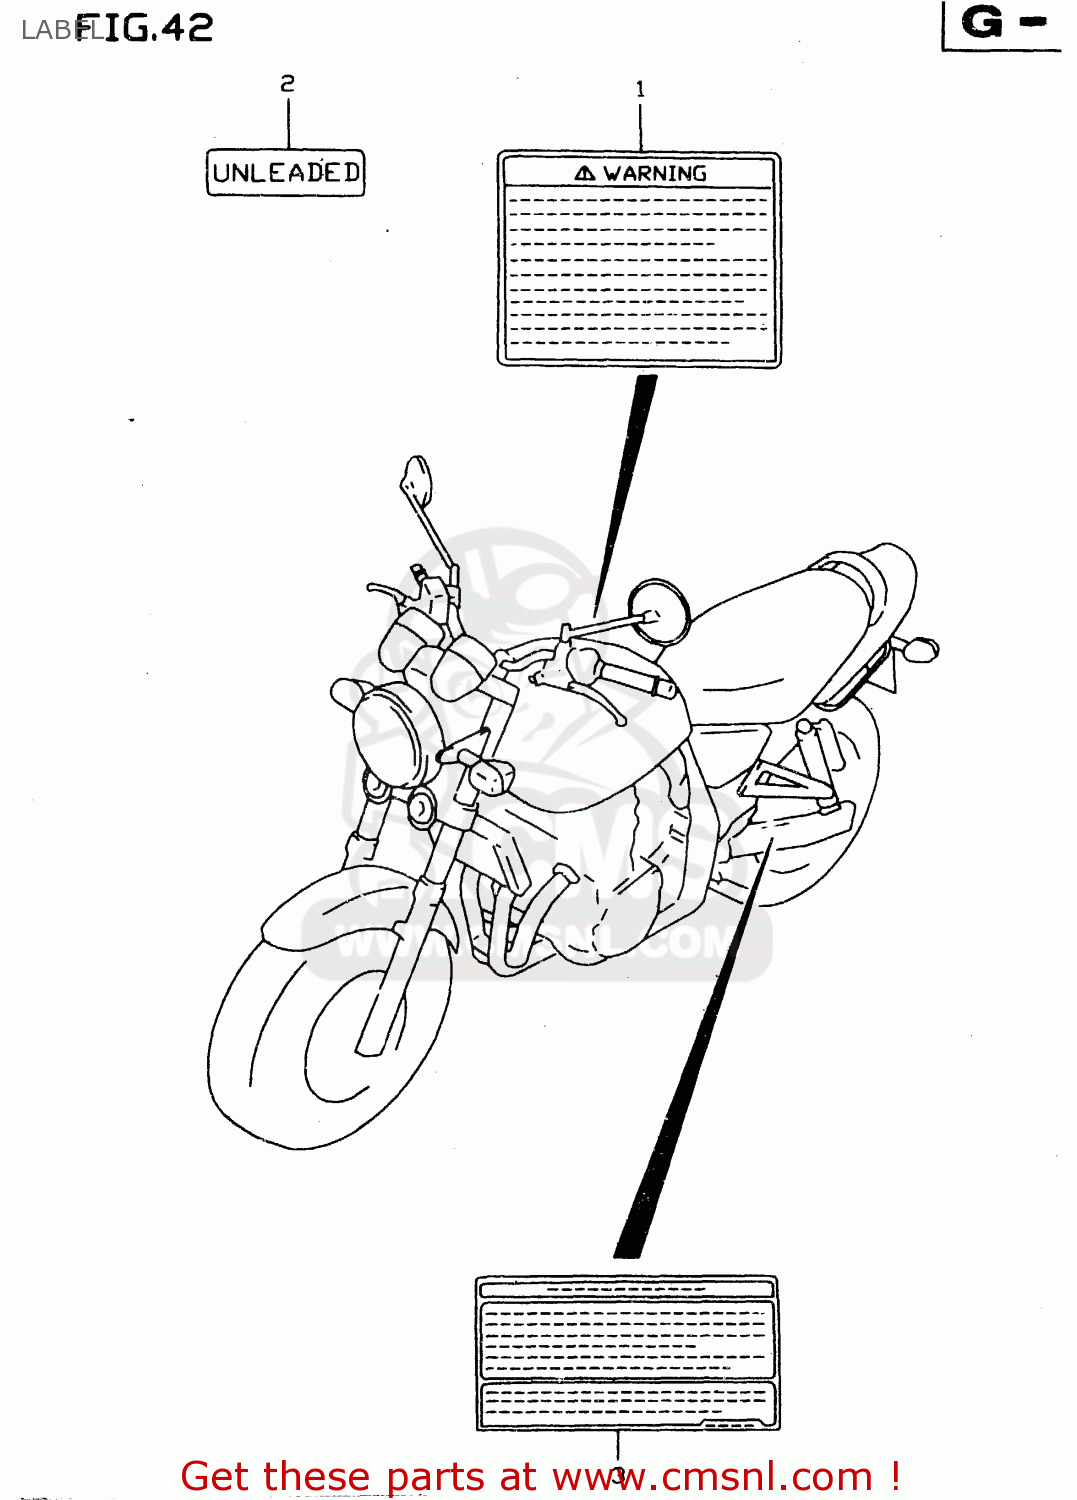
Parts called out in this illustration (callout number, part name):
1	LABEL,WARNING
2	LABEL,CAUTION
3	LABEL, TIRE INFORMATION
4	O.M. GSX750 W
